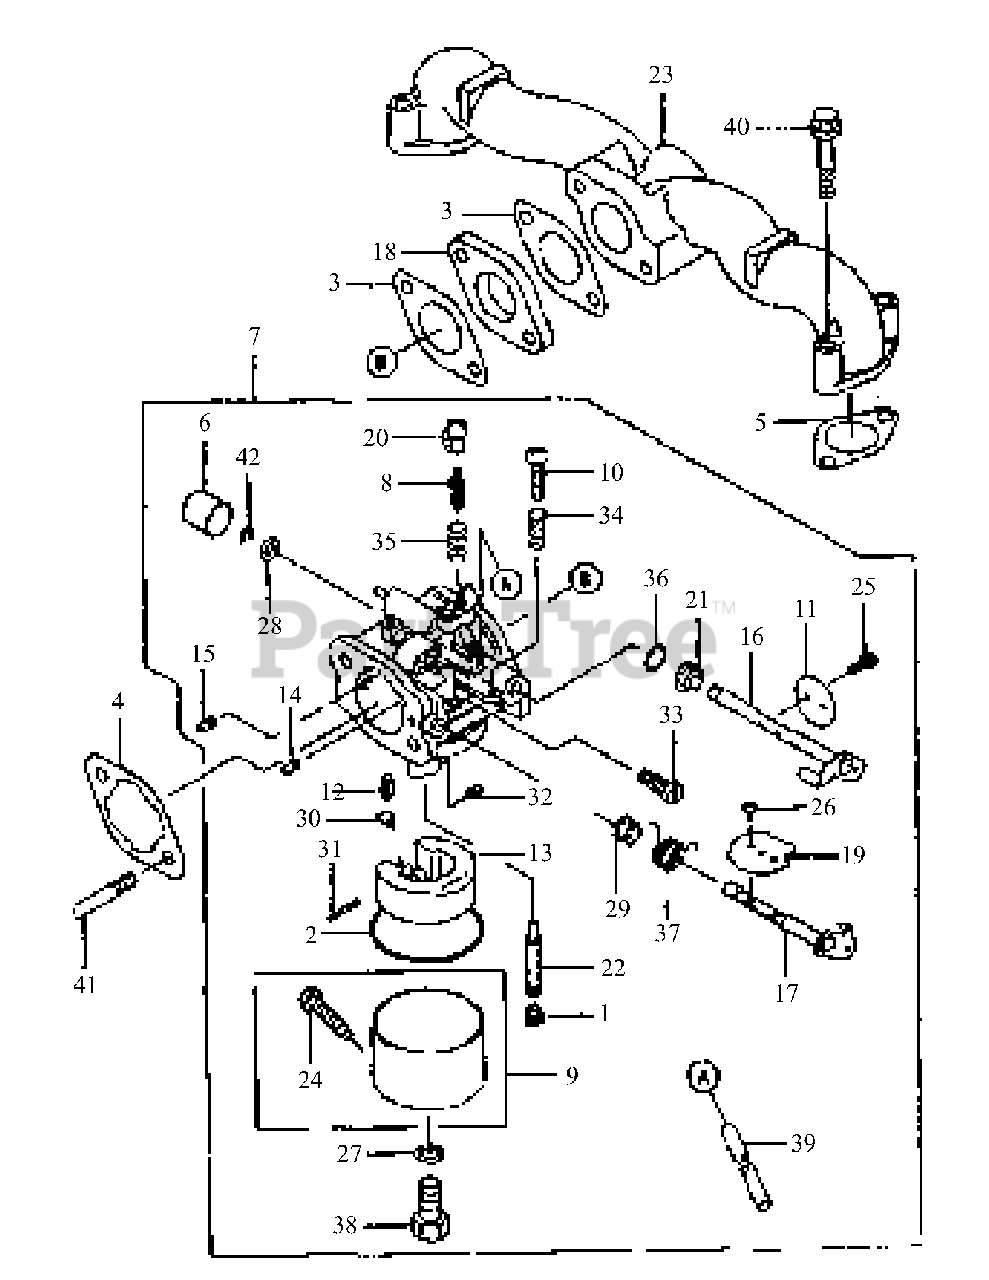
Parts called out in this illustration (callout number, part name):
3	Gasket, Insulator
4	Gasket, Air Filter
8	Screw, Pilot Air
9	Chamber, Float
10	Screw, Throttle Stop
11	Valve,Throttle#130
14	Jet, Air #1.7
15	Jet, Air# 1.2
16	Shaft, Carburetor
17	Shaft, Carburetor
18	Insulator
22	Nozzle, Main #113A
23	Manifold, Intake
32	Jet, Main #125
33	Jet, Pilot #44.8
40	Bolt, Flange
42	Circlip, Type E
